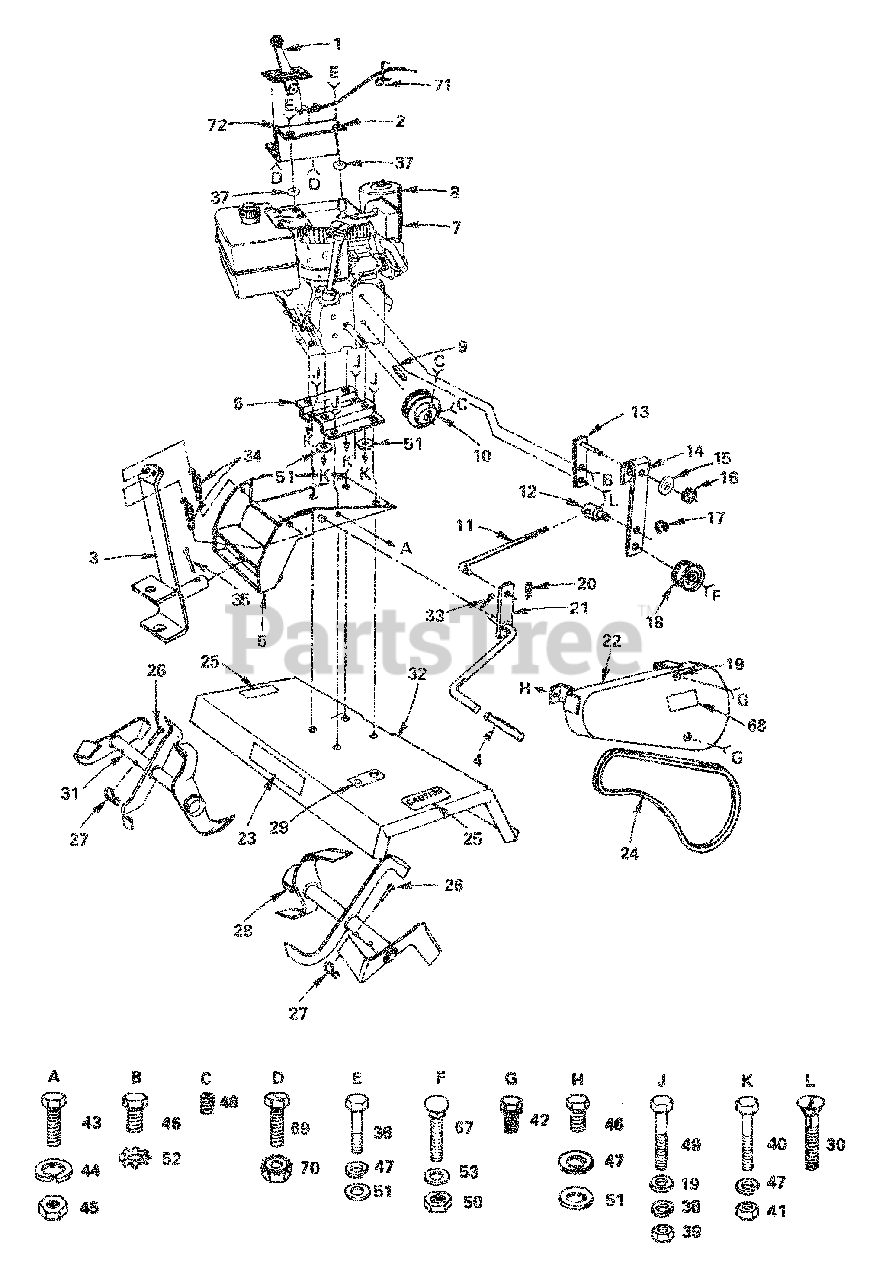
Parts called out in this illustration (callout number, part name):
1	Control Throttle
2	Bracket, Throttle Control
3	Hitch Yoke Assembly
4	Grip, Handle
5	Hitch Channel Assembly
6	Plate, Adapter
7	Engine 8 H.P., Tecumseh
8	Decal, Instruction, Engine
9	Square Key 1/4 x 1-1/4
10	Engine Sheave
11	Belt Tightener Link
12	Adjusting Pin
13	Idler Support Plate and Pivot
14	Idler Arm
15	Washer 15/32 x 11/16 x 16 Ga.
16	E-Ring
18	Idler Pulley
19	Washer 13/32 x 7/8 x 14 Ga.
20	Clip, Hairpin
21	Lever and Arm
22	Belt Guard and Supports
25	Decal, Caution
26	Drilled Pan Hd. Rivet 3/8 x 1-3/4
27	Clip, Hairpin
28	Tine Weldment, L.H.
29	Decal, On/Off
30	Screw, Fl. Hd. Mach. 5/16-24
31	Tine Weldment, R.H.
32	Tine Shield
33	Cotter Pin 5/32 x 1
34	Spring
35	Cotter Pin 1/4 x 1-1/2
36	Bolt, Hex 5/16-18 x 1 Gr. 2
37	Washer 13/32 x 13/16 x 11 Ga.
38	Washer Lock, Hvy. Hel. Spring
39	Nut, Hex 3/8-16 UNC
40	Bolt, Hex 5/16-18 x 1-1/2 Gr. 2
41	Nut, Hex 5/16-18 UNC
42	Hex Bolt with Sems Ext. Washer Lock 5/16-18 UNC x 3/4
43	Hex Bolt 1/4-20 x 1
44	Washer Lock 1/4
45	Hex Nut 1/4-20 UNC
46	Hex Bolt 5/16-24 x 3/4
47	Washer Lock 5/16
48	Hex Socket Set Screw 5/16-18x3/8
49	Hex Bolt 3/8-16 x 1-1/2
50	Hex Lock Nut 3/8-16 UNC
51	Washer 11/32 x 11/16 x 16 Ga.
52	Washer Lock External Tooth 5/16
67	Bolt, Carriage 3/8-16 x 1-3/4
69	Screw
70	Nut, Keps #10-24 UNC
71	Clip - Insulated
72	Decal, Throttle
72	Decal, Oper./Lubrication (Engine)
72	Decal, Tecumseh Logo (Engine)
